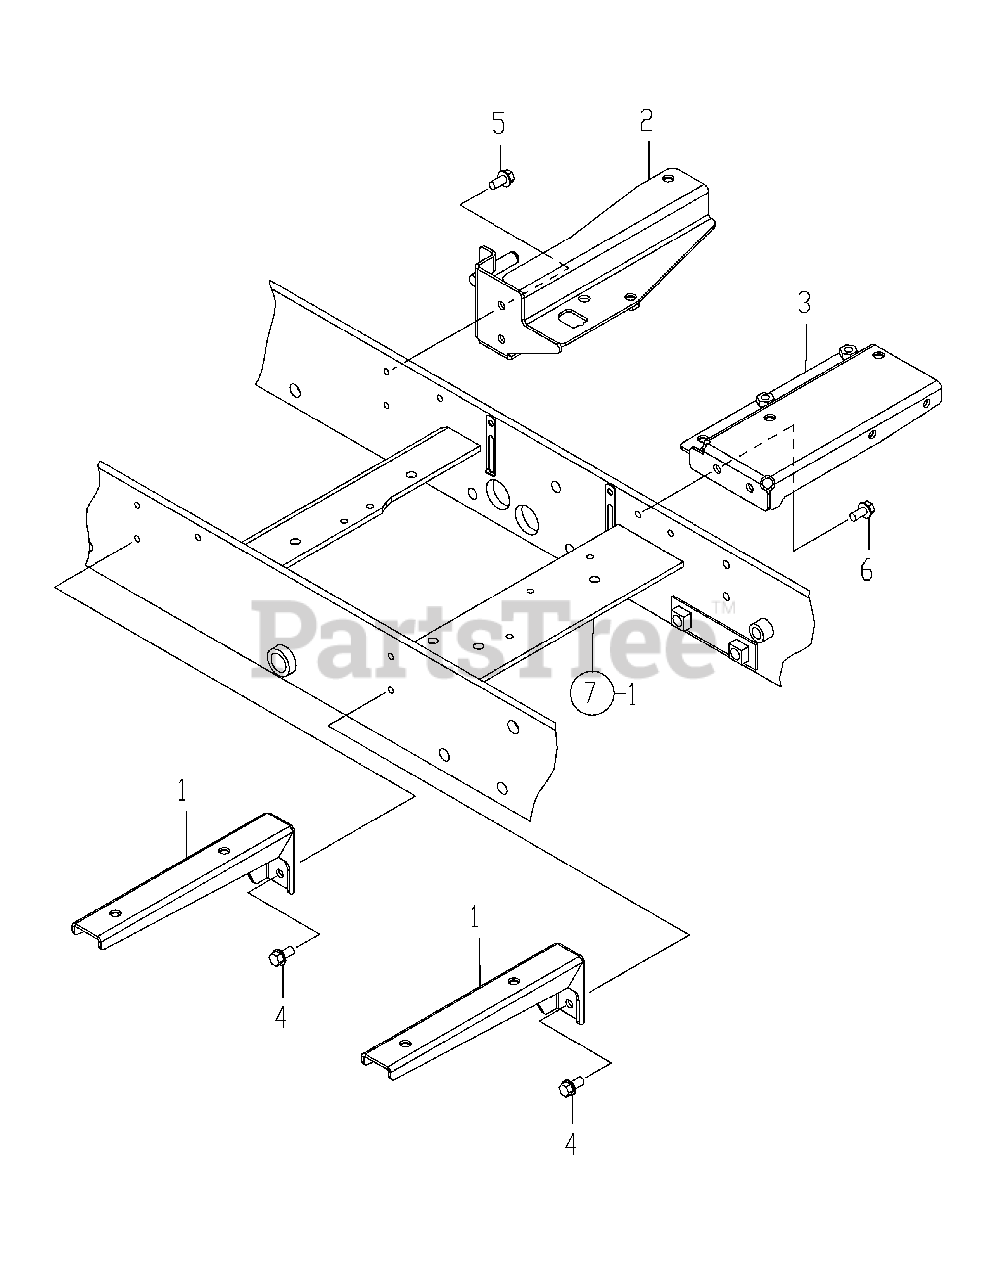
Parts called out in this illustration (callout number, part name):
1	STAY L, STEP CMP
2	STAY RF, STEP CMP
3	STAY RR, STEP CMP
